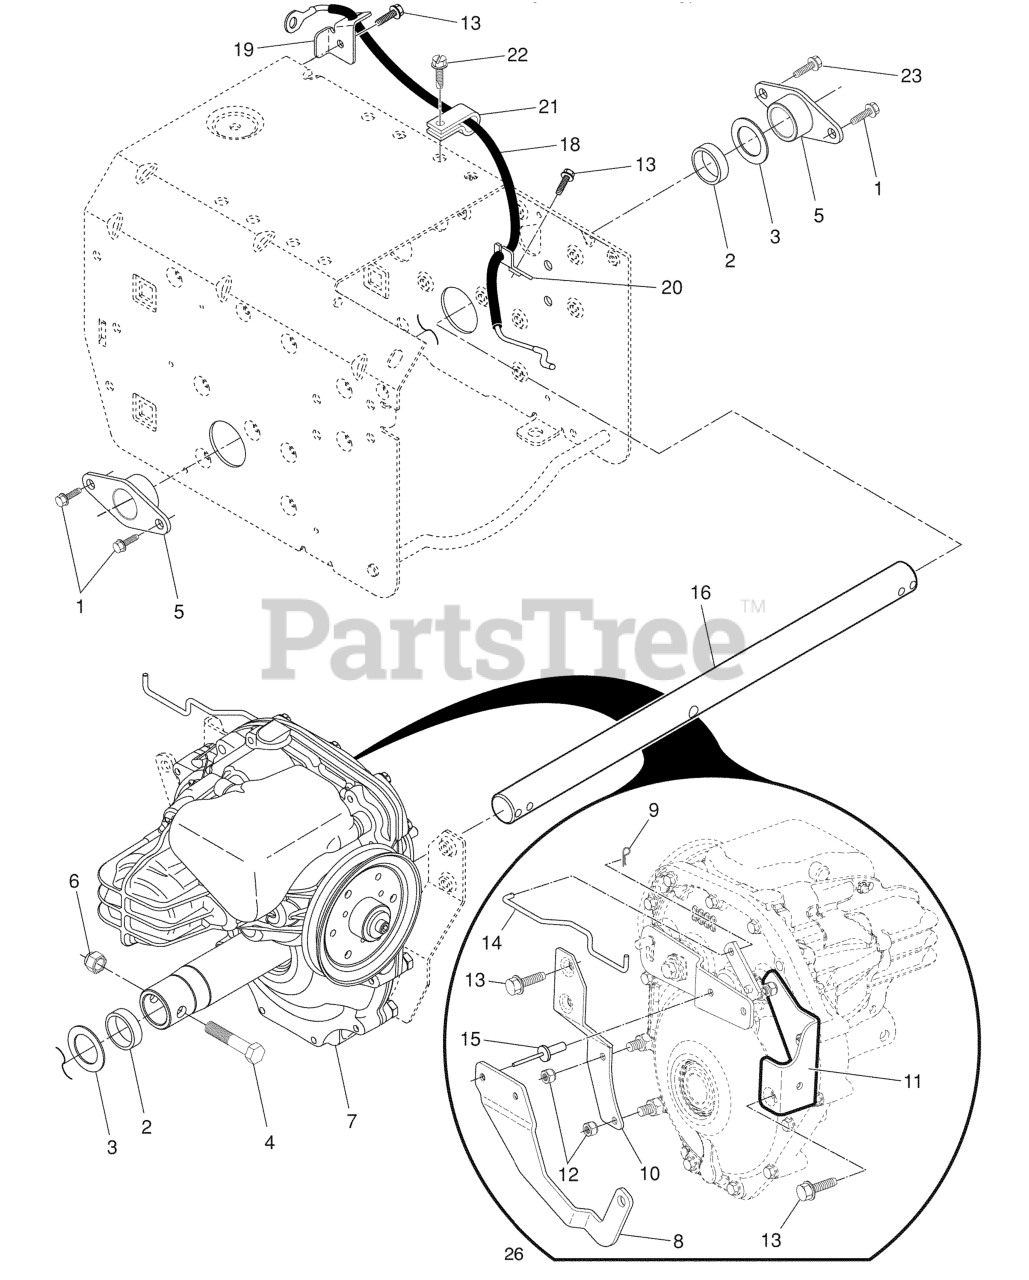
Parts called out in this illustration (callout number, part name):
1	Screw, Hex Head 5/16-18 x 3/4
2	SPACER.AXLE.RH
3	WASHER TRUST 1"
4	CAP.SCREW.HEX.HD.3/8-16
5	BEARING, AXLE
6	LOCKNUT
7	TRANSMISSION.HYDRO.SNOW
8	ARM.CONTROL.HYDRO.SNOW
9	RETAINER CLIP
10	TORQUE STRAP
11	BRACKET, ANTI-ROTATE
12	LOCKNUT.NYLOC.1/4-20
13	SELF-TAPPING SCREW 5/16-18X3/4
14	ROD, BYPASS VALVE
15	RIVET.POP.1/4X.475
16	SHAFT.AXLE.POWER.STEERING.HYD
18	CABLE.DRIVE.CONTROL.SNOW
19	BRACKET.CABLE.REAR.SNOW
20	BRACKET, CABLE, FRONT
21	GUIDE CLIP PM
22	SCREW, SLOTTED HEX HEAD 1/8 X
